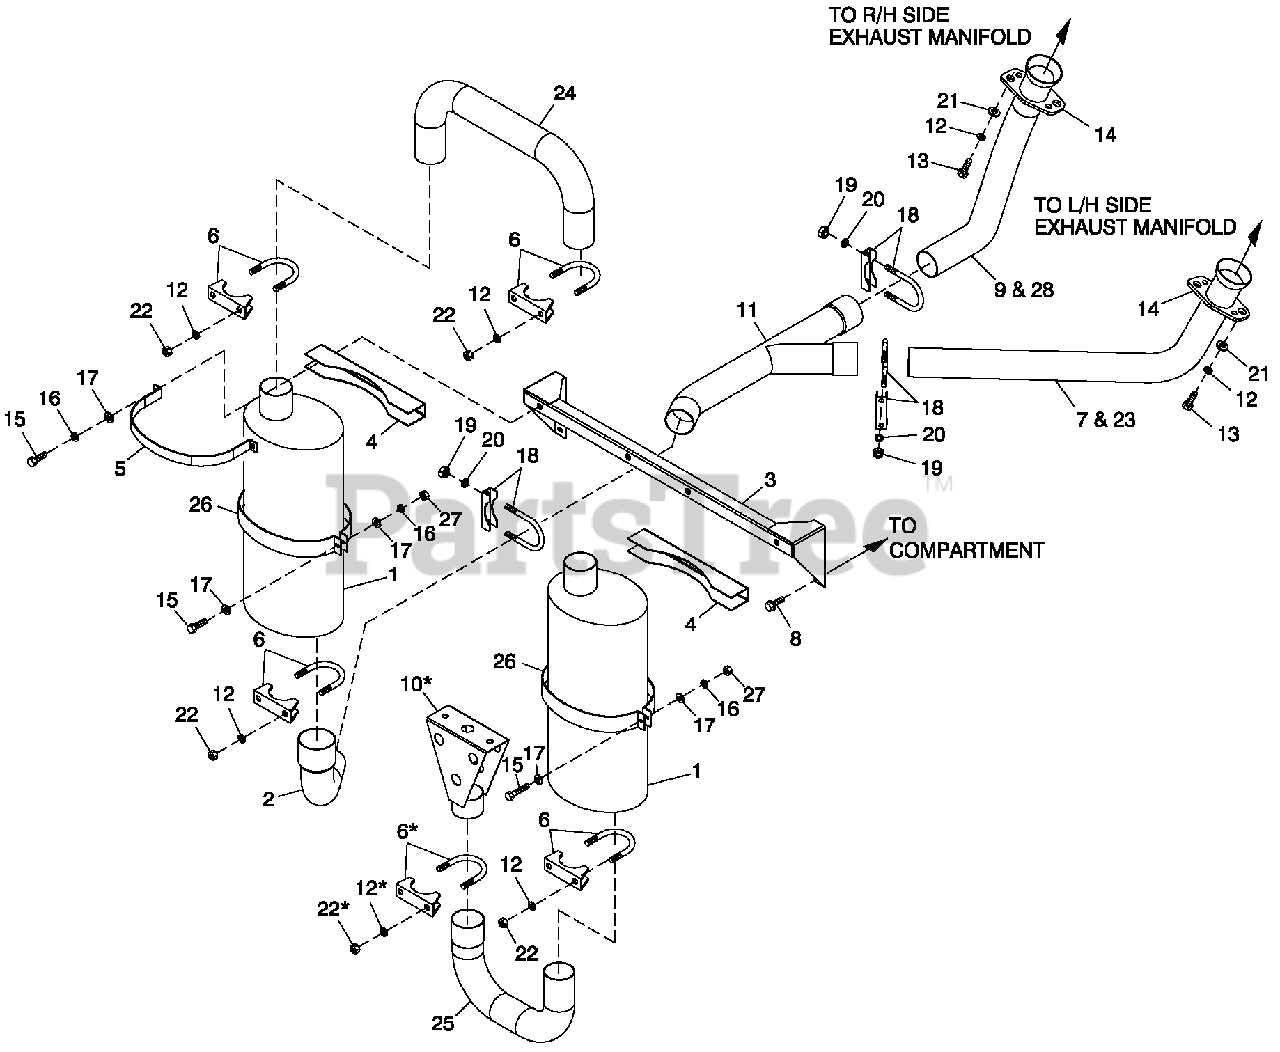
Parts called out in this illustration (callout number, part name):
1	MUFFLER 7" X 9" X 18-1/2" 2" IN/OUT
2	EXHAUST ELBOW 2"ID X 2-1/2"OD
3	BRAC KET MUFFLER
4	MUFFLER BRACKET STIFFENER
5	MUFFLER STRAP
6	BOLT U 3/8-16X2.62
7	PIPE EXHAUST LEFT 2"OD
8	SCREW THF M6-1 X 16 N WA Z/JS
9	PIPE EXHAUST RIGHT 2"OD
10	DIFFUSER EXHAUST WELDMENT
11	Y-PIPE EXHAUST 2"OD 4.2L G3
12	WASHER LOCK 3/8 SS
13	SCREW HHC M10-1.5 X 45 SS FTH
14	EXHAUST FLANGE 2" PIPE
15	SCREW HHC M6-1.0 X 35 G8.8 BLK
16	WASHER LOCK M6-1/4
17	WASHER FLAT 1/4-M6 ZINC
18	BOLT U 5/16-18X2.25
19	NUT HEX 5/16-18 STEEL
20	WASHER LOCK M8 SS
21	WASHER FLAT 3/8 SS
22	NUT HEX 3/8-16 STEEL
24	PIPE EXHAUST CROSSOVER
25	PIPE EXHAUST MUFFLER OUT
26	MUFFLER STRAP UPPER/LOWER
27	NUT HEX M6 X 1.0 G8 YEL CHR
